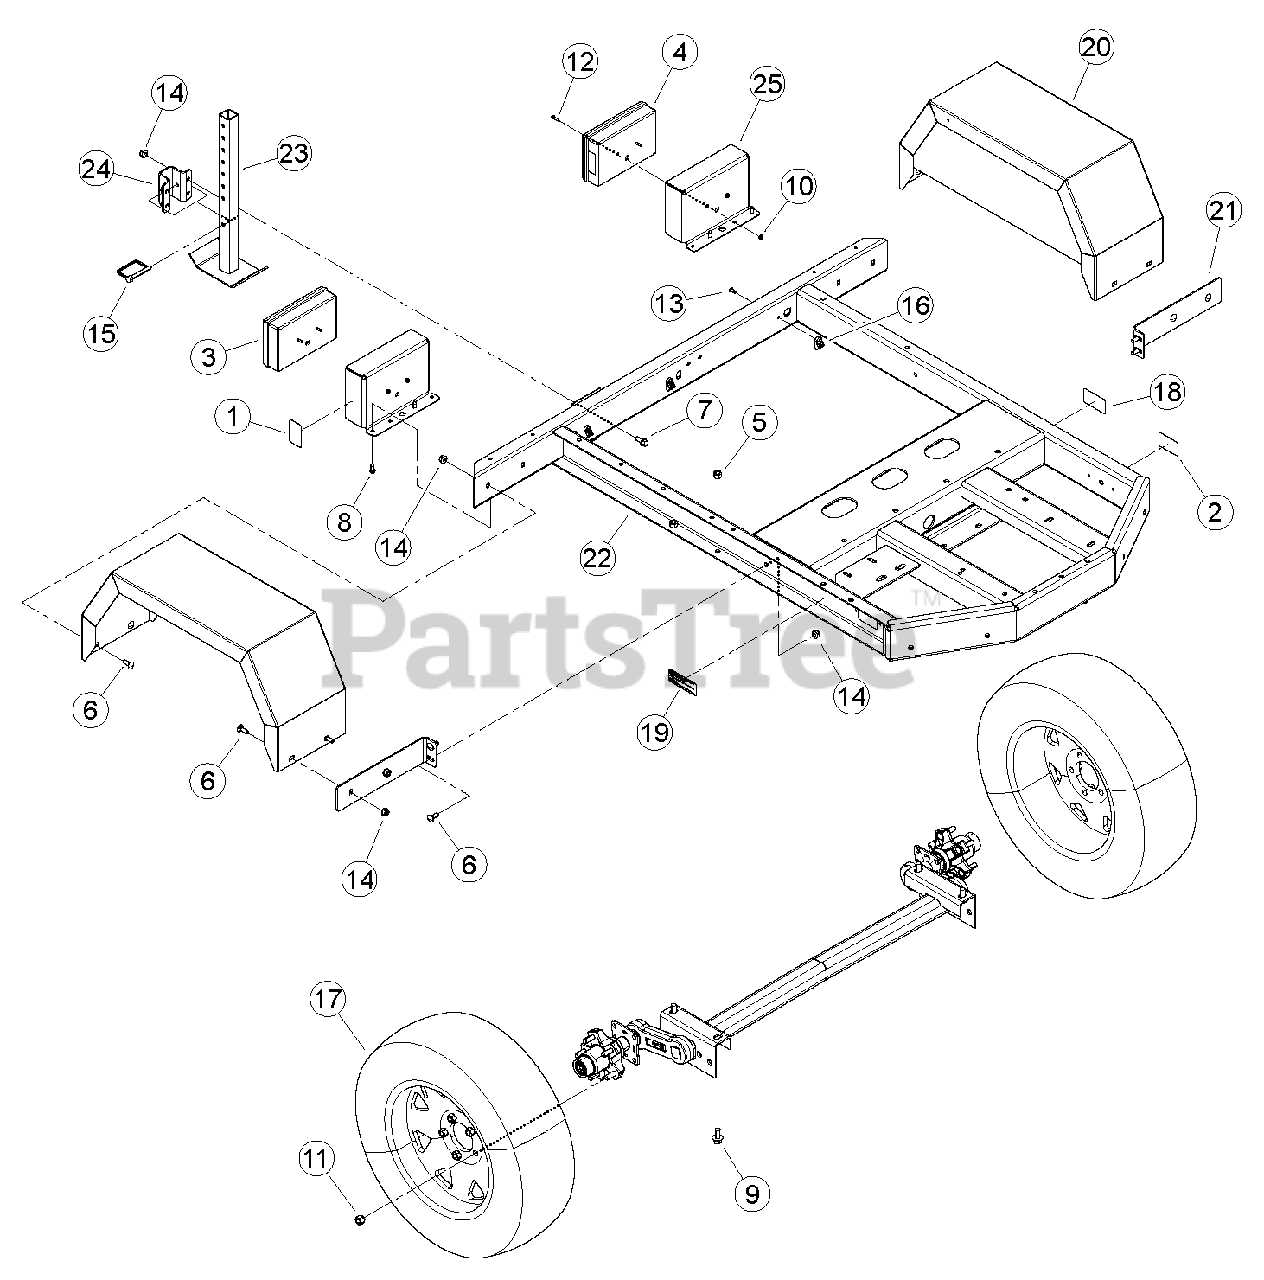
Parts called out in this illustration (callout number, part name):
1	REFLECTOR, WIDE ANGLE RED
2	REFLECTOR, WIDE ANGLE AMBER
3	LIGHT, TAIL RH
4	LIGHT, TAIL LH
5	NUT, 1/2-13 GR5 CENTERLOCK GRB
6	BOLT, 3/8-16 X 1 GR5 CRG
7	BOLT, 3/8 X 1 FLANGE NC
8	SCREW, 11/32-12 X 7/8 HWH T-AB
9	BOLT, 1/2-13 1.00 GR5 FLANGE NC
10	NUT, 10/24 NYLOCK TYPE NM ZP
11	NUT, 1/2-20 WHEEL
12	BOLT, 10-24 X 3/4" HHCS GR8 PLAIN
13	RIVET, AL BLIND 1/4 X 3/4 DOME HEAD
14	NUT, 3/8-16 NYLOCK FLANGE
15	PIN, 3/8 X 2-1/2 LYNCH
16	CLAMP, CABLE MOUNT
17	ASSEMBLY, TIRE AND WHEEL 14 IN
18	DECAL, P205/75R14 LOAD RATING
19	DECAL, EPA EVAP
20	WELDMENT, 6" CHIPPER FENDER
21	BRACKET, 6" FENDER
22	WELDMENT, 6" CHIPPER TRAILER
23	WELDMENT, REAR STABILIZER
24	GUIDE, TRAILER SUPPORT
25	BRACKET, TAIL LIGHT
